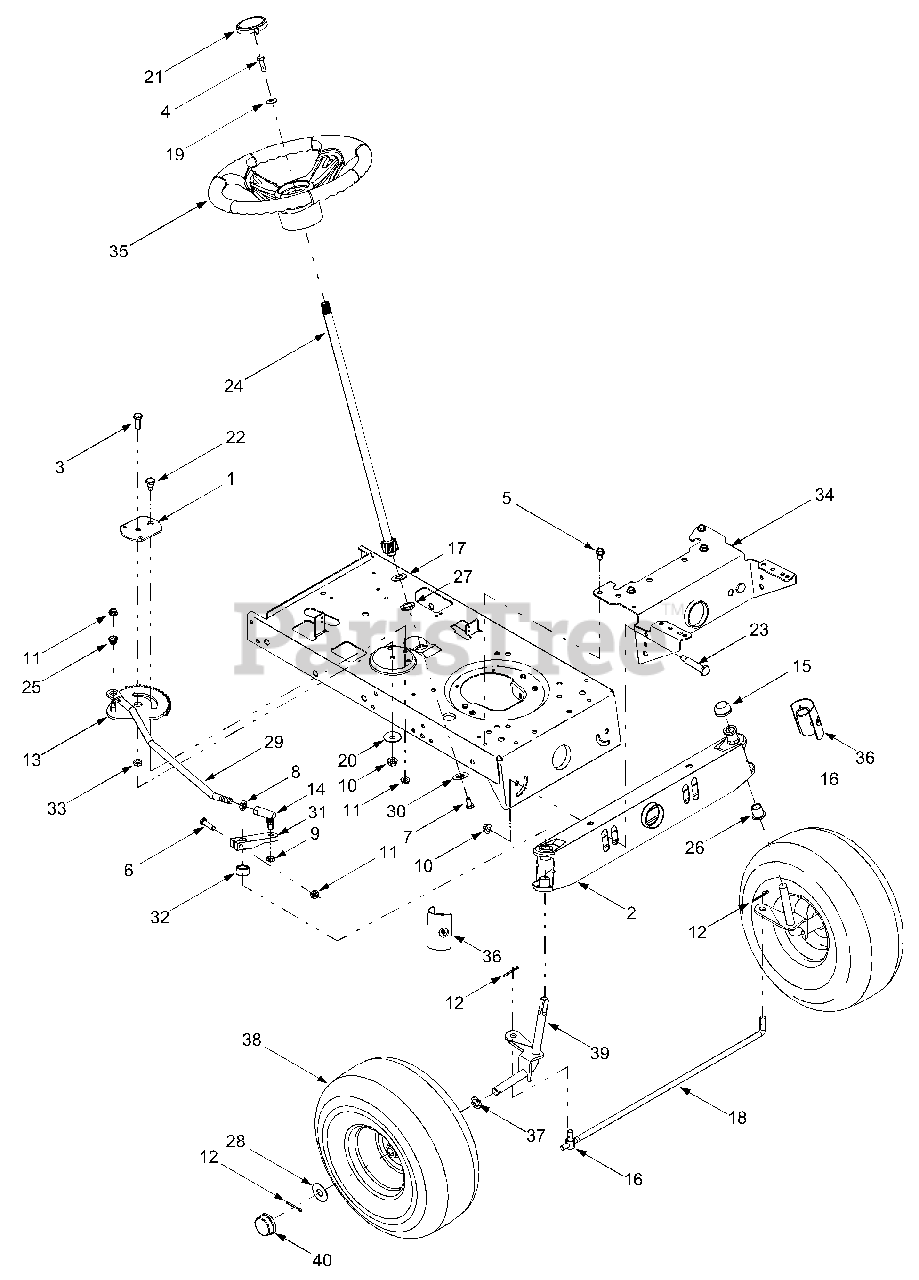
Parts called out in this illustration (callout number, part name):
1	Retainer Gear Segment Plate
4	Hex Cap Screw, 5/16-18 x 1.0
5	Self-tapping Screw, 5/16-12 x .75
6	Hex Cap Screw, 5/16-18 x 1.5
7	Machine Screw, 5/16-18 x .75
8	Jam Nut, 7/16-20 (Grade 2)
9	Jam Nut, 3/8-24
10	Flange Lock Nut, 3/8-16
11	Flange Lock Nut, 5/16-18
12	Cotter Pin, 1/8 x 1.25
13	Steering Segment Gear
14	Ball Joint, 7/16 -20
15	Push Cap, .625
16	Ferrule, 3/8-24 x .437 Dia
17	Flat Washer, .64 x 1.24 x .060
18	Tie Rod, Adjustable
19	Bell Washer, .34 x .872 x .060
20	Bell Washer, .391 x .380 x .062
21	Steering Wheel Cap w/ Spring, Small
22	Shoulder Screw, .435 x .350, 5/16-18
23	Shoulder Screw, .498 x 2.045
24	Steering Shaft, 21.86
25	Plastic Bushing, .38 ID
26	Flange Bushing, .632 ID
27	Hex Flange Bearing, 5/8
28	Flat Washer, .635 x 1.589 x .06
29	Steering Drag Link, 7/16-20
30	Cap, 1.25 x .16
31	Steering Arm
32	Spacer, 1.0 x .645 x .56
33	Spacer, .380 x .625 x .21
36	Axle End Cap, w/ Fitting
37	Flat Washer, .64 x 1.0 x .12
40	Hub Cap
